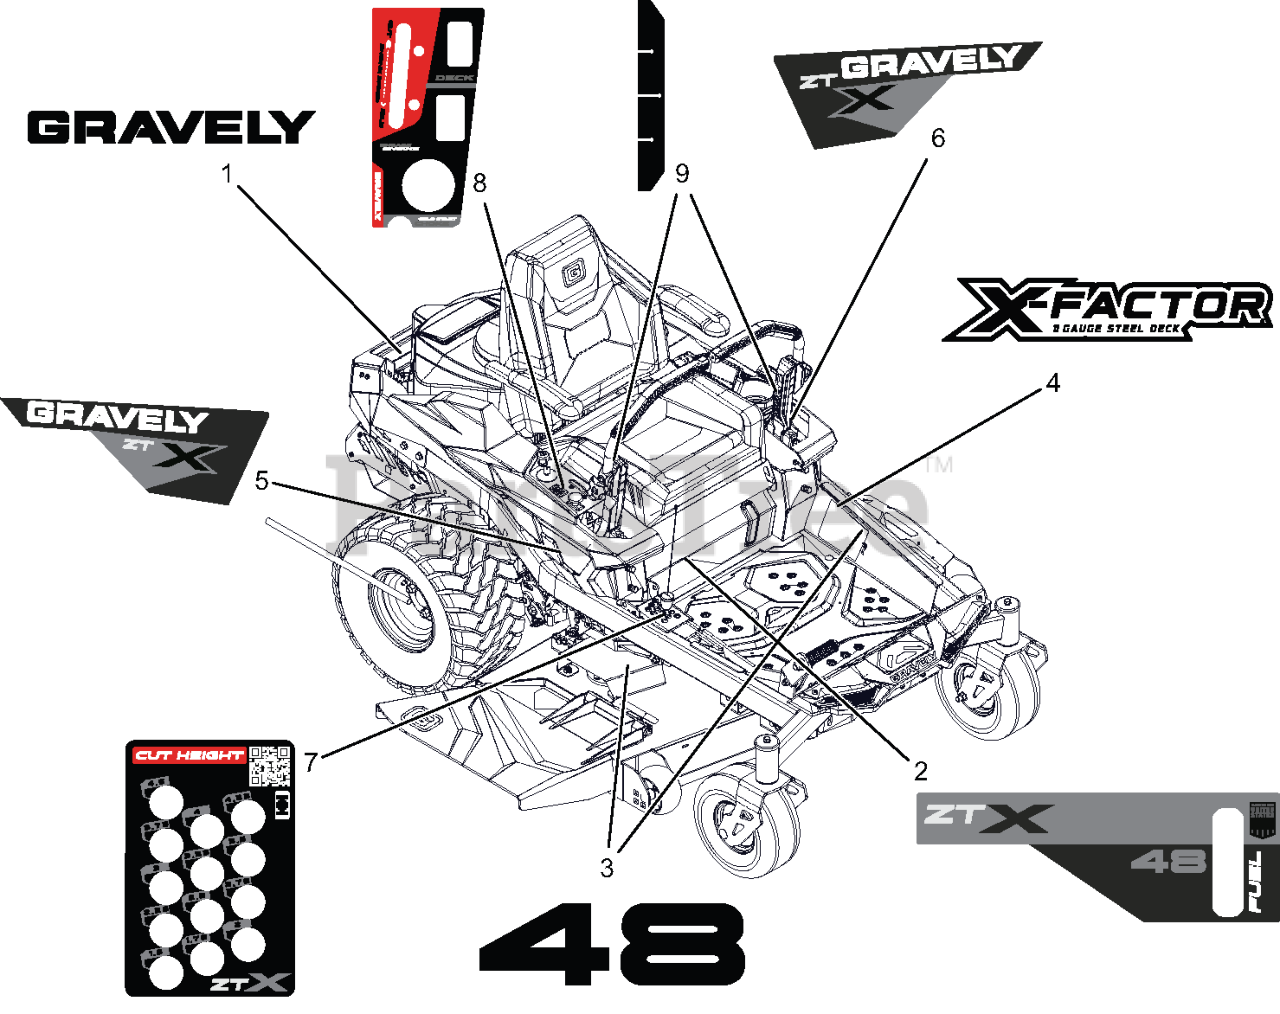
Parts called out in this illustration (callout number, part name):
1	DECAL- GRAVELY
2	DECAL- ZTXL 48-KICK PLATE
3	DECAL- DECK 48"
4	DECAL- DECK X-FACTOR
5	DECAL- ZT X FENDER RH
6	DECAL- ZT X FENDER LH
7	DECAL- HEIGHT OF CUT-X
8	DECAL- CONTROL PANEL-GRAVELY
9	DECAL- HIRTH INDICATOR
